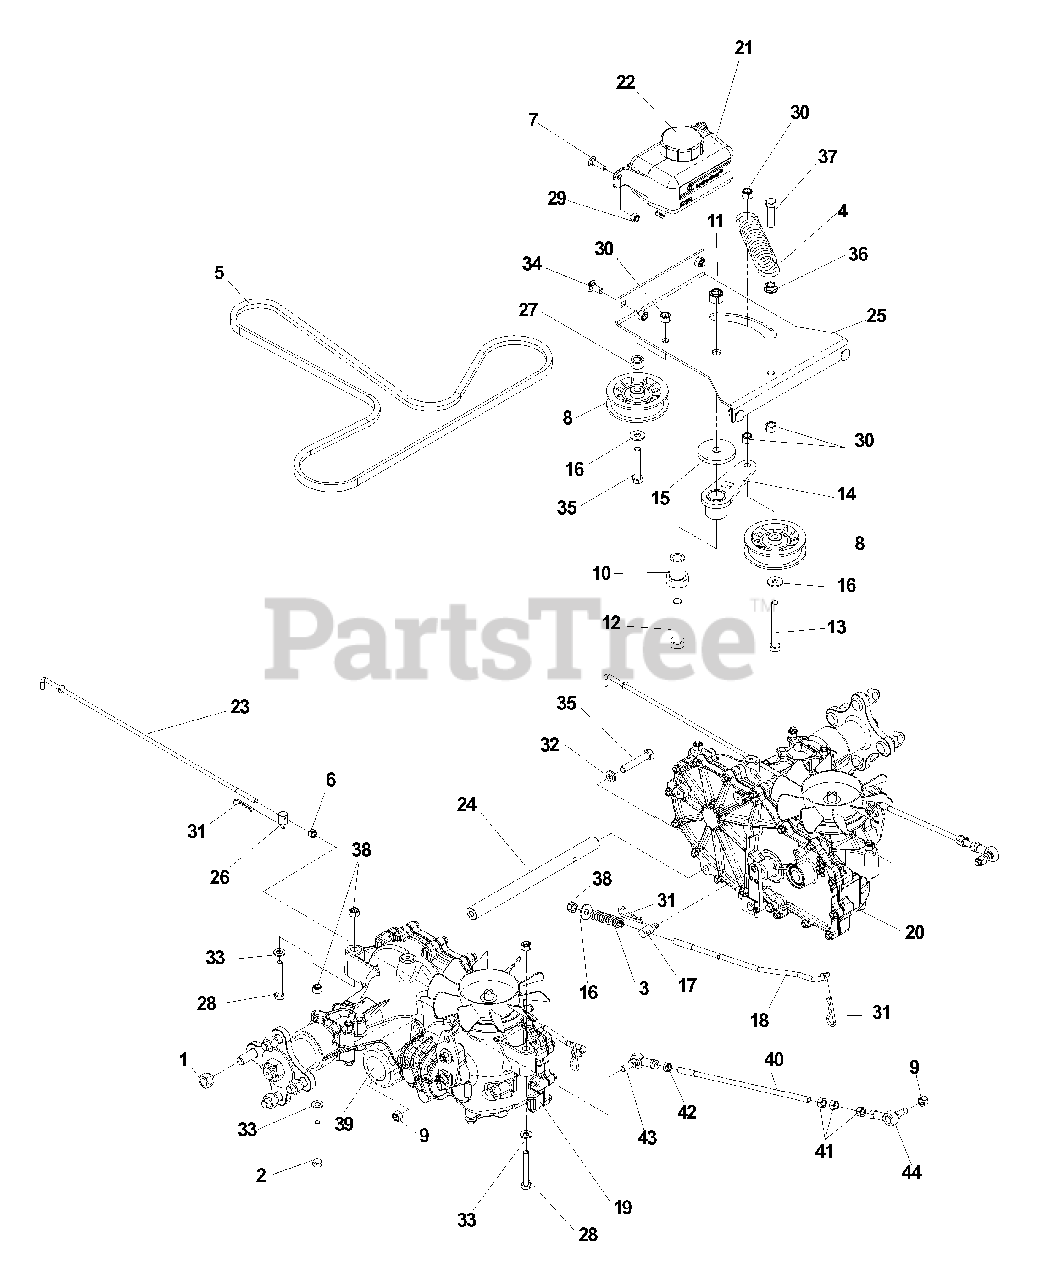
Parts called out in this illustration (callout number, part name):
1	NUT, 1/2-20, LUG
2	HCS, 5/16-18 X 2 3/4, GR5
4	SPRING EXTENSION
5	BELT, PUMP
6	NUT, 1/4-28
7	RHSNB, 1/4-20 X 1, GR5
8	PULLEY, IDLER
9	NUT, 5/16, NYLOC
10	SPINDLE, IDLER
11	NUT, 1/2-13, NYLOC
12	HCS, 1/2-13 X 2 3/4, GR5
13	HCS, 3/8-16, GR5
14	IDLER ARM
15	HEAVY WASHER
16	WASHER, 5/16
17	BRAKE SWIVEL
18	BRAKE LINKAGE
19	RIGHT
20	LEFT
21	EXPANSION TANK W/CAP
23	BYPASS LINKAGE
24	2800 CROSS SUPPORT
25	IDLER PULLEY PLATE
26	SWIVEL, 1/4-28
28	HCS, 5/16-18 X 2 1/4, GR5
29	NUT, 1/4-20, NYLOC
30	NUT, 3/8-16, NYLOC
31	PIN, HAIR, .073 X 1 7/16
32	WASHER, 3/8
33	WASHER, 5/16, SAE
34	RHSNB, 5/16-18 X 3/4, GR5
35	HCS, 3/8-16 X 2, GR5
36	NUT, 3/8-16, WHIZLK
37	HCS, 3/8-16 X 1 1/2, GR5
38	NUT, 5/16-18, NYLOC
39	OIL FILTER
40	DRIVE LINKAGE
41	NUT, 5/16-24
42	NUT, 5/16-24, LH
43	ROD END, LEFT
44	ROD END, RIGHT
